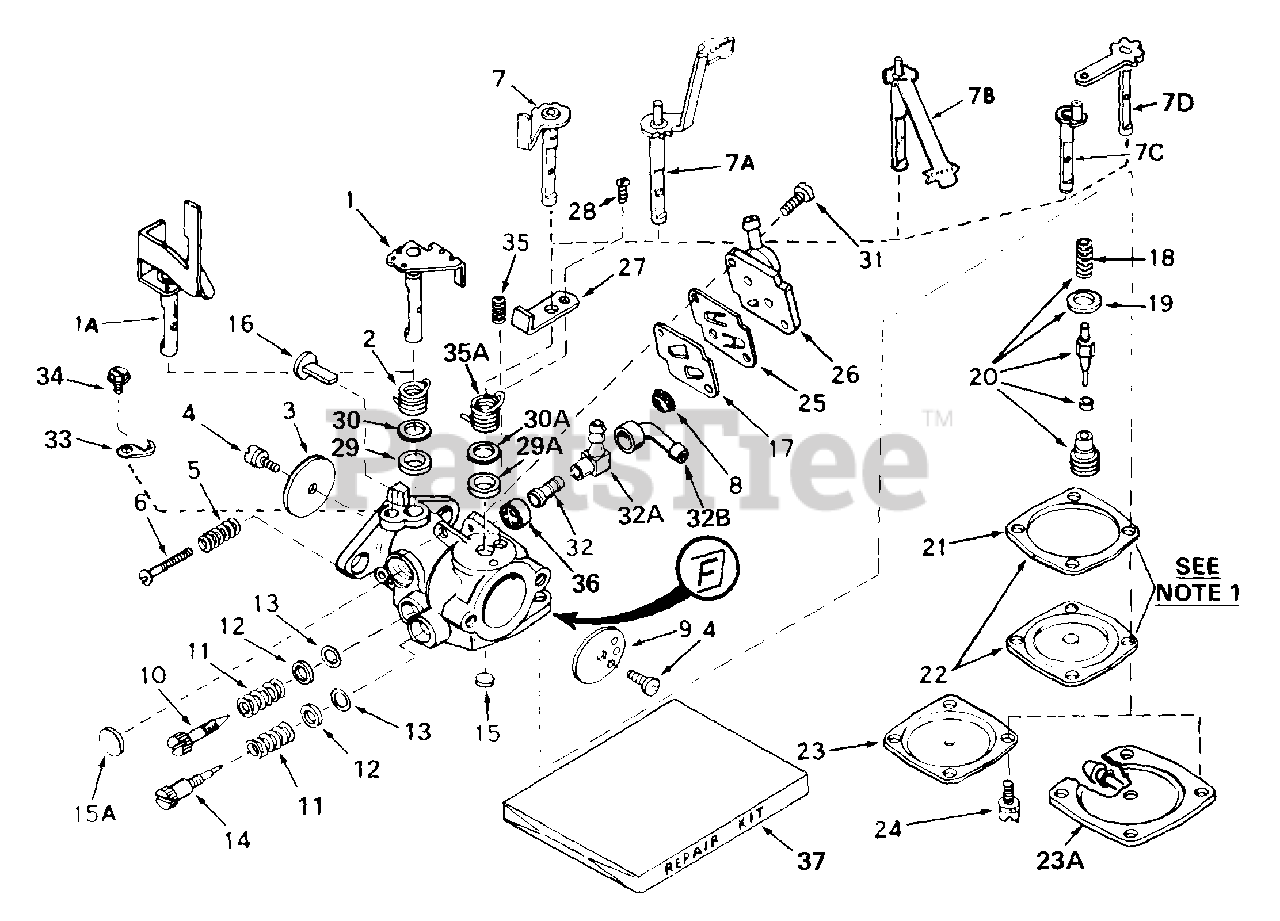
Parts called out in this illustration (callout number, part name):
1	"Shaft & Lever Assy., Throttle
2	Spring, Throttle return
3	Shutter, Throttle
4	Screw, Throttle & Choke shutter
5	Spring, Idle regulating screw
6	Screw, Idle regulating
7	Shaft & Lever Assy., Choke
8	Screen, Filter
9	Shutter, Choke
10	Screw, Idle adj.
11	Spring, Adj. screw
12	Spring, Adj. screw
13	"O" Ring, Adj. screw
14	Screw, Main adj.
15A	Plug, Welch
16	Element, Pump
17	Gasket
18	Spring, Valve
19	Gasket, Valve seat
20	Inlet Needle, Seat, Spring & Gasket A ssy.
21	Gasket, Diaphragm
22	Diaphragm Assy.
23	Cover, Diaphragm
24	Screw, Diaphragm cover
25	Valve, Flap
26	Cover Assy., Valve
27	Spring, Detent
28	Screw, Detent spring
31	Screw, Valve cover
33	Retainer, Throttle shaft
34	Screw, Retainer
37	Repair Kit
